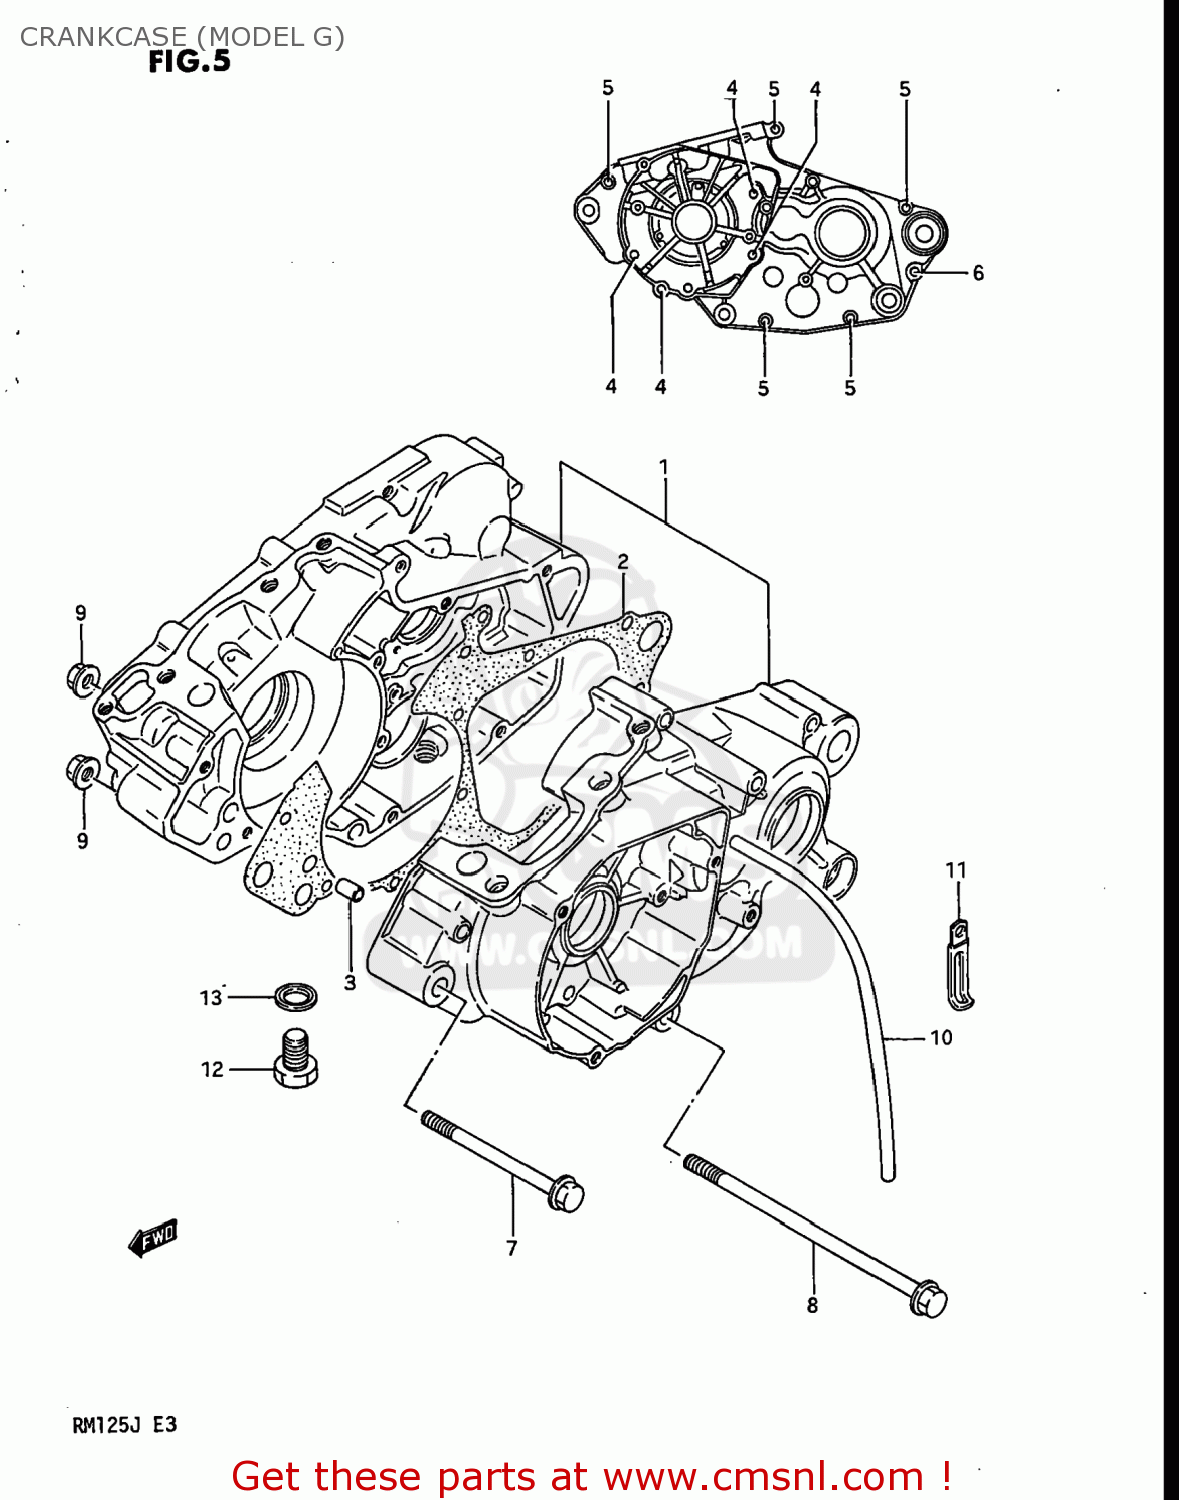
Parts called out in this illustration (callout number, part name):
1	CRANKCASE SET
2	GASKET,CRANKCASE (MCA)
3	PIN
4	SCREW (6X45)
5	SCREW
6	SCREW 6X60
7	BOLT(8X95)
8	BOLT(8X150)
9	NUT
10	HOSE
11	CLAMP
12	PLUG
13	GASKET(14X19.2X2) (NAS)
